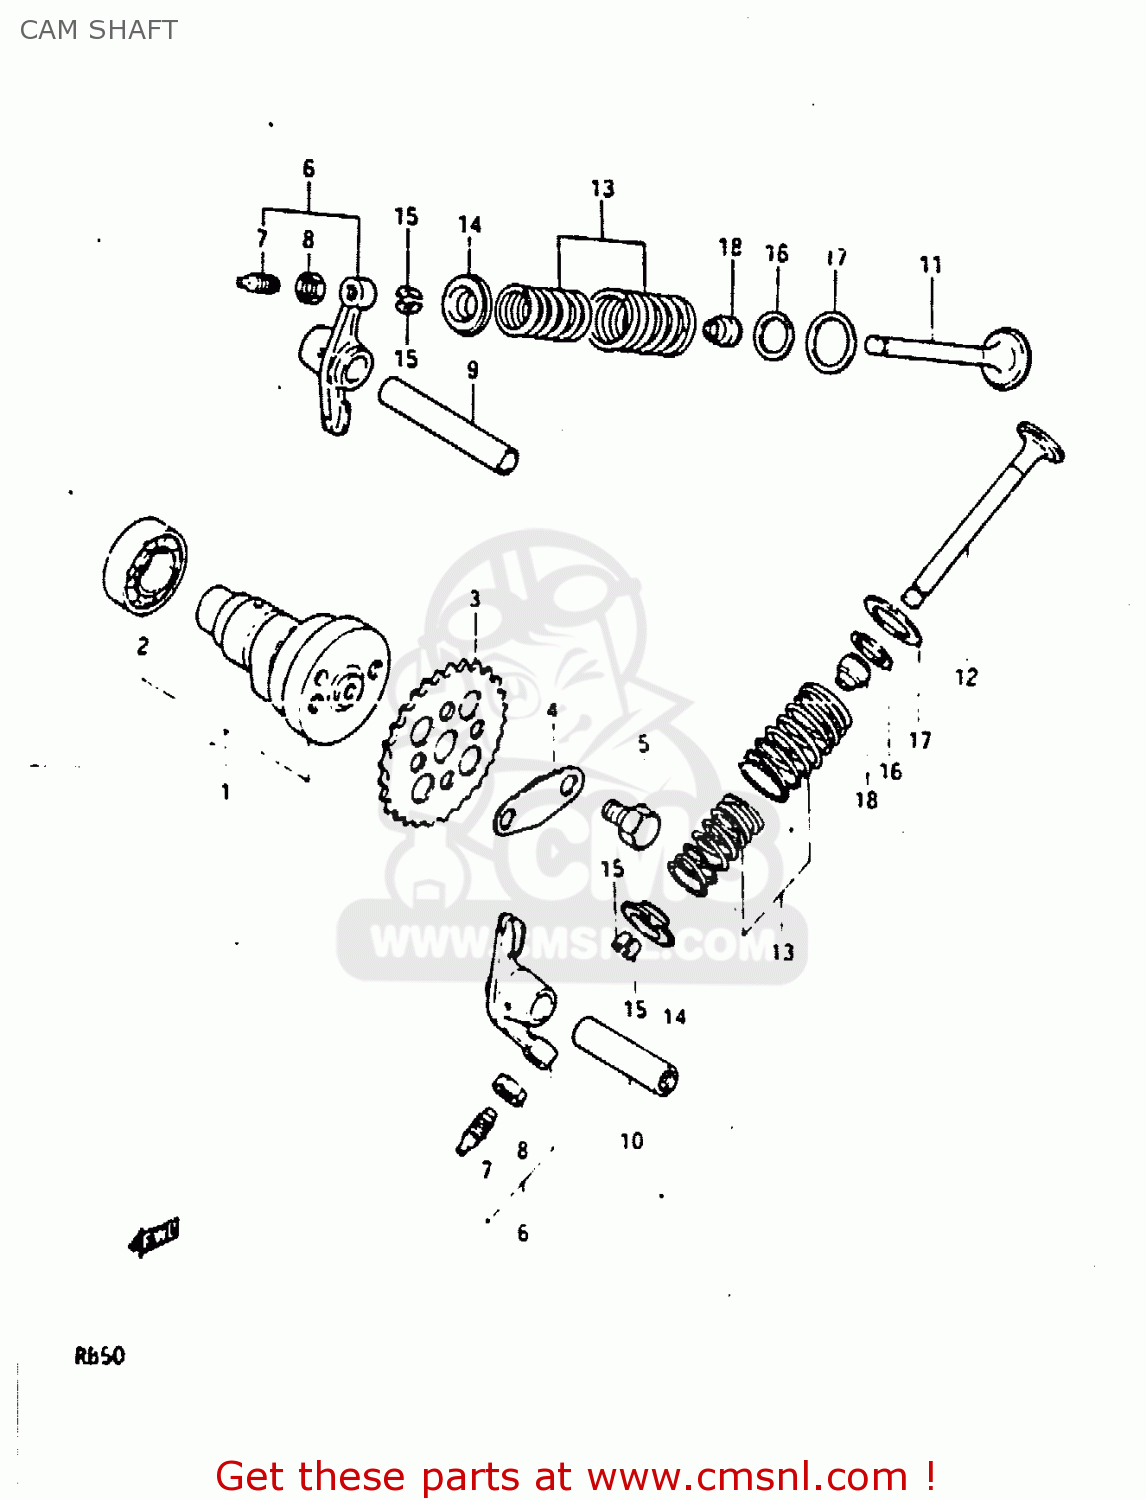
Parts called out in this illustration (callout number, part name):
1	CAMSHAFT ASSEMBLY
2	BEARING(15X32X9)
3	SPROCKET,CAMSHAFT
4	WASHER,SPROCKET
5	BOLT(6X10.5)
6	ARM,VALVE ROCKER
7	SCREW,TAPPET ADJUSTING
8	NUT,ADJUSTING
9	SHAFT,VALVE ROCKER ARM INTAKE
10	SHAFT,VALVE ROCKER ARM EXHAUST
11	VALVE,INTAKE
12	VALVE,EXHAUST
13	SPRING SET,VALVE
14	RETAINER,VALVE SPRING
15	COTTER VALVE
16	SEAT,VALVE SPRING INNER
17	SEAT,VALVE SPRING OUTER
18	SEAL,OIL(5X10.5X8.4)
